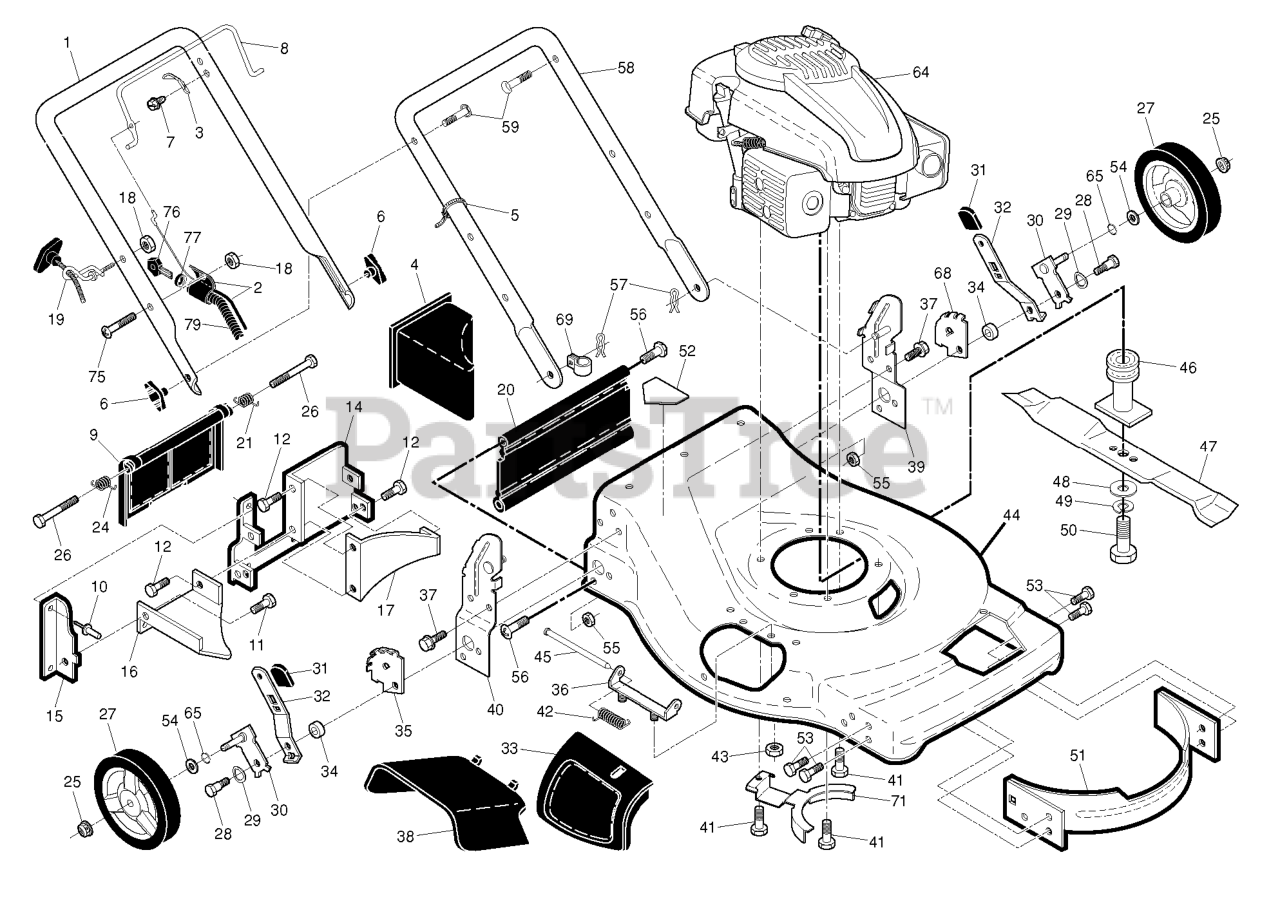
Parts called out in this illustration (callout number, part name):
1	HANDLE.ASM.UP.CREASED.GRE.W/GR
2	CABLE.MZR.W/KEY.START SW.51.62
3	BRACKET UPSTOP
4	PLUG.MULCH.22RD
5	TIE GUIDE
6	KNOB, DEFLECTOR
8	CONTROL BAR
9	REAR DOOR ASSY
10	RIVET BLIND
11	SCREW.HXTAP.10-24
12	SCREW 14-20 X 5/8
14	PLATE.BACK
15	SIDE BAFFLE
16	DISCHARGE BAFFLE
17	REAR BAFFLE
18	NUT
19	RB GUIDE.ROPE.STD.BLK.ZIN WSL
20	SKIRT.REAR.22RD/SD.FO/VE
21	SPRING.LH.22.REAR.DOOR.EZ.EMPT
24	SPRING.RH.22.REAR.DOOR.EZ.
25	NUT.HEX.FLANGE.3/8-16.LO(3 2)
27	WHEEL & TIRES ASSY, FRONT
28	BOLT SHOULDER 3/8 -16X1
29	WASHER.CURVED.CYLINDRICAL
30	AXLE ARM ASSY.
31	SELECTOR KNOB
32	SELECTOR SPRING, FRONT
33	DOOR.MULCH.22.REAR.FWGD.GREY
34	SPACER.HEIGHT.ADJUSTER
35	WHEEL ADJUSTING BRACKET
36	BRACKET.ASM.HINGE.21.FWGD.
37	BOLT.HEX.HD.WASHER.5/16-18X.75
38	DEFLECTOR.CLIPPING.22.FGD
39	BRACKET.ASM.HDL.LT.EZEM.22.ORA
40	BRACKET.ASM.HDL.RT.EZEM.22.ORN
41	BOLT 3/8-16X1-1/8
42	SPRING.TORSION
43	LOCKNUT.NYLOC.1/4-20
44	HOUSING.22.TORUS.FWD.ORANGE.WA
45	ROD.HINGE.21
46	RP ADAPTER.BLADE.25MM.21F
47	BLADE.22.MULCH.STANDARD
48	WASHER,HARDEN
49	LOCKWASHER
50	SCREW, HEX HD 3/8-24 X 1-3/8
51	FRONT BAFFLE KIT
52	DANGER DECAL
53	SCREW 1/4X20
54	WASHER.FLAT.1/2
55	LOCKNUT
56	HINGE SCREW
57	HAIRPIN COTTER
58	HANDLE.LOWER.PNT
59	BOLT, HANDLE 5/16-18X1.75
65	O-RING..070X.487.NEOPRENE
68	WHEEL ADJUSTING BRACKET LH
69	CLIP.CABLE.BLK
71	BRACKET.KEEPER.BELT
75	SCREW.(COMBINATION CONTROL)
76	KEY.MOLDED
77	NUT.CAP.SNAP-ON.KEY START
79	HARNESS.WIRING.CONTROL
